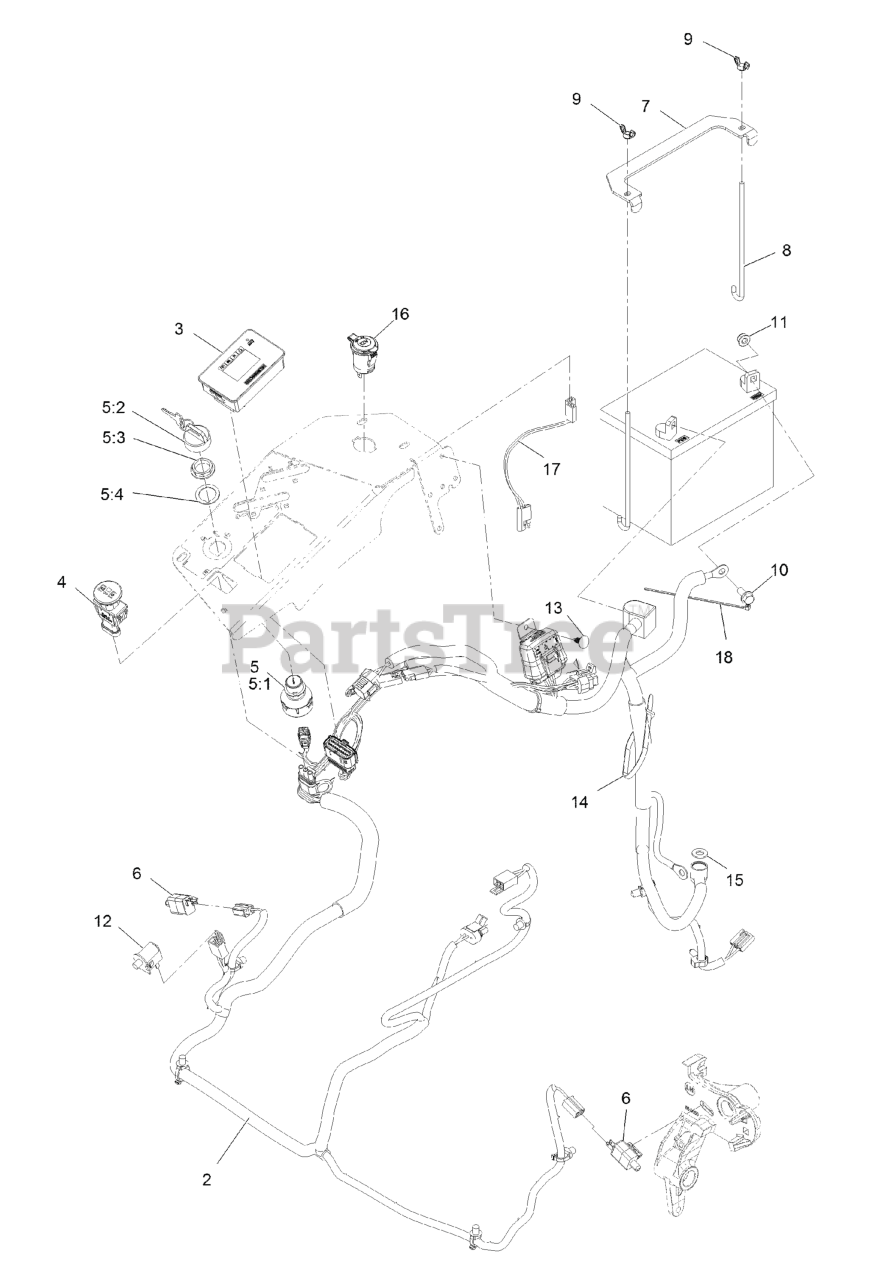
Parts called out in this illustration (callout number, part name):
2	WIRE HARNESS ASM
3	Meter-Hour
4	SWITCH-PTO, SEALED
5	IGNITION SWITCH ASM
5:1	Switch-Ignition
5:2	NUT-MOUNTING
5:3	IGNITION KEY SET
5:4	WASHER-BACKUP
7	STRAP-TIE DOWN, BATTERY
8	BOLT-HOLDDOWN
9	WINGNUT
10	SCREW-HHF
11	NUT-HF, NI
12	SWITCH-BAIL
13	PLUG-PLASTIC
14	TIE-PLASTIC
15	WASHER-FLAT
16	PORT-POWER, 12V
17	HARNESS-RECEPTACLE, 12V
18	TIE-CABLE
